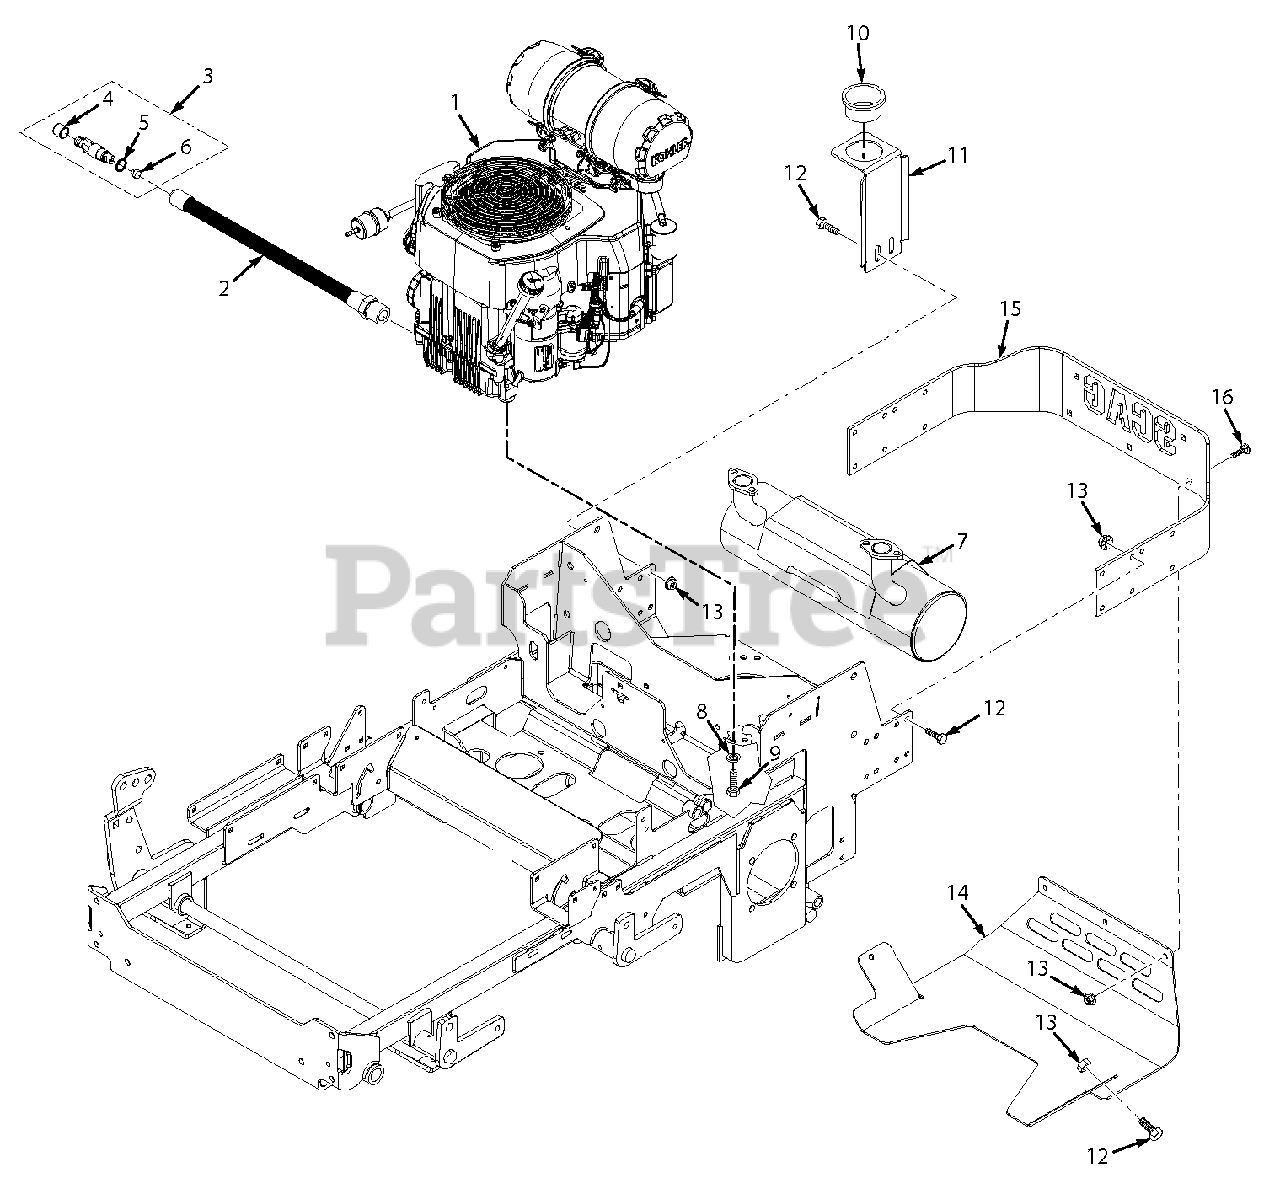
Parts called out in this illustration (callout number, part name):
1	Engine, Kawasaki 22FS
1	Engine, Kawasaki 22FX
1	Engine, Kawasaki 23FX
1	Engine, Kohler 23CV
1	Engine, Kohler 25CV-EFI
1	Engine, Kohler 26CV-EFI
2	Hose, Oil Drain - Kawasaki FX / FS
2	Hose, Oil Drain - Kohler CV & CV-EFI
3	Valve Assembly, Oil Drain
5	O-Ring
7	Muffler, Kawasaki FS/FX
7	Muffler, Kohler 23CV
7	Muffler, Kohler 25CV-EFI & 26CV-EFI
8	Lockwasher, 3/8" Spring, Kawasaki FX / FS
9	Bolt, Hex Head 3/8-16 x 1-1/4", Kawasaki FX / FS
9	Bolt, Hex Head 3/8-16 x 1-1/4" Self Tap, Kohler CV & CV-EFI
10	Bushing, Thick Panel Snap
11	Bracket, Oil Drain Hose
12	Bolt, Hex Head 3/8-16 x 1"
13	Nut, Serrated Flange 3/8-16
14	Plate, Skid
15	Bumper, Rear
16	Bolt, Carriage 3/8-16 x 1"
